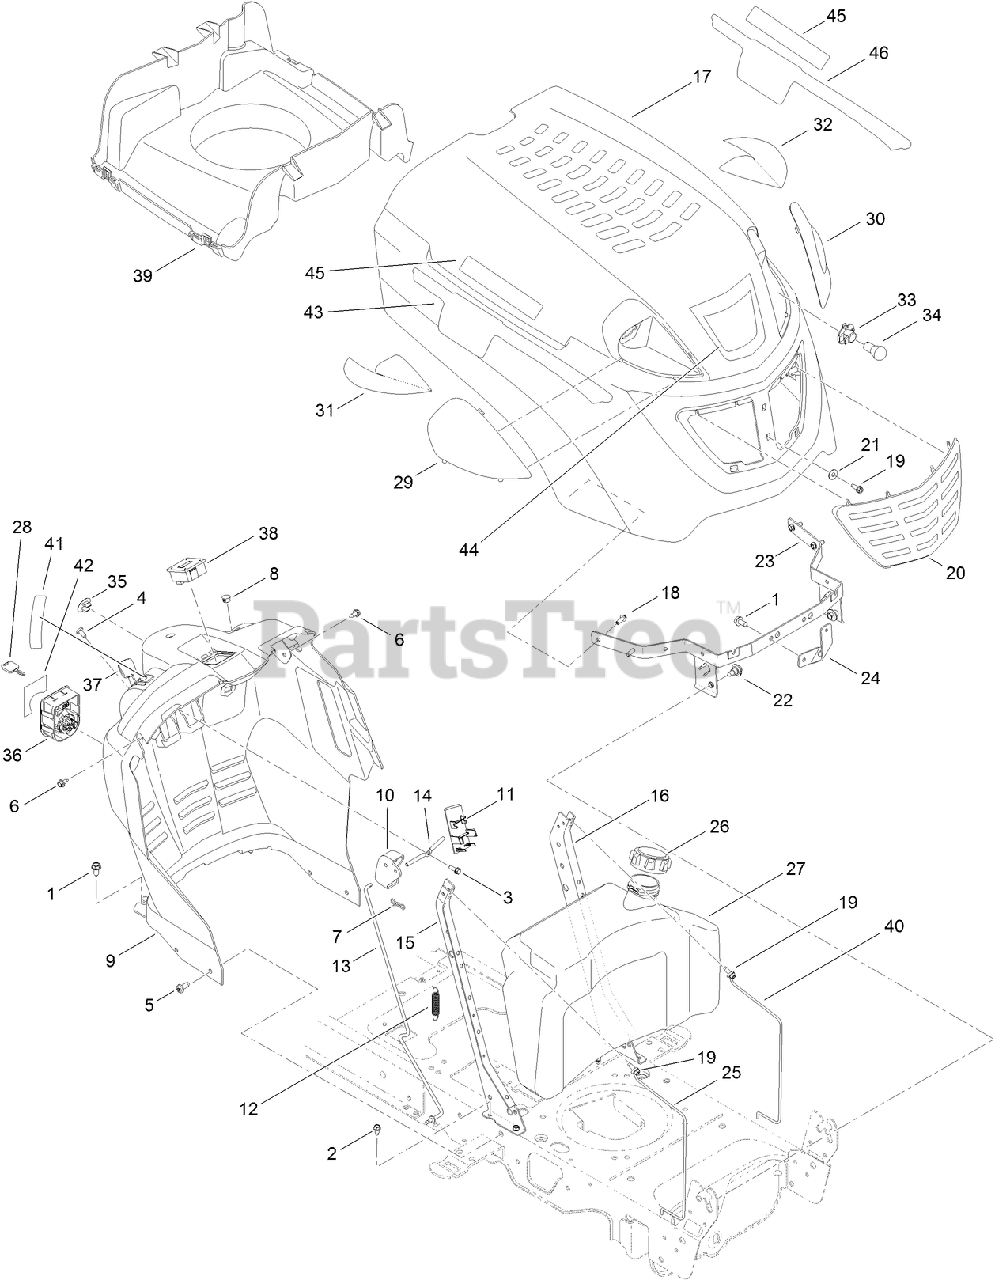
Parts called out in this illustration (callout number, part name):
1	SCREW-TAP
2	SCREW-HWHTF
3	SCREW-TAP
4	SCREW-TAP
5	SCREW-TAP
6	SCREW-HWH
7	PIN-COTTER
8	CAP-PLUG, HOLE
9	DASH-MANUAL, PTO
10	LEVER-DASH
11	COVER-CRUISE
12	SPRING-EXTENSION
13	ROD-LATCH
14	ROD-LEVER, BENT
15	SUPPORT-DASH, PLATE (RH)
16	SUPPORT-DASH, PLATE (LH)
19	SCREW-TAP
21	WASHER-FLAT
22	BOLT-SHOULDER, TAP
23	BRACKET-PIVOT
24	BRACKET-SUPPORT, HOOD
25	ROD-SUPPORT
26	CAP-FUEL
27	TANK-FUEL
28	KEY-IGNITION
29	LENS-RH
30	LENS-LH
31	REFLECTOR-RH
32	REFLECTOR-LH
33	SOCKET-HEADLIGHT
34	LAMP-12V, MINIATURE
35	PLUG-CHOKE
36	MODULE-SWITCH, IGNITION
37	CABLE-THROTTLE/CHOKE
38	METER-HOUR
39	PLENIUM-HOOD
40	ROD-SUPPORT, LH TANK
41	DECAL-THROTTLE
43	DECAL-HOOD, RIGHT SIDE
44	DECAL-HOOD
46	DECAL-HOOD, LEFT SIDE
